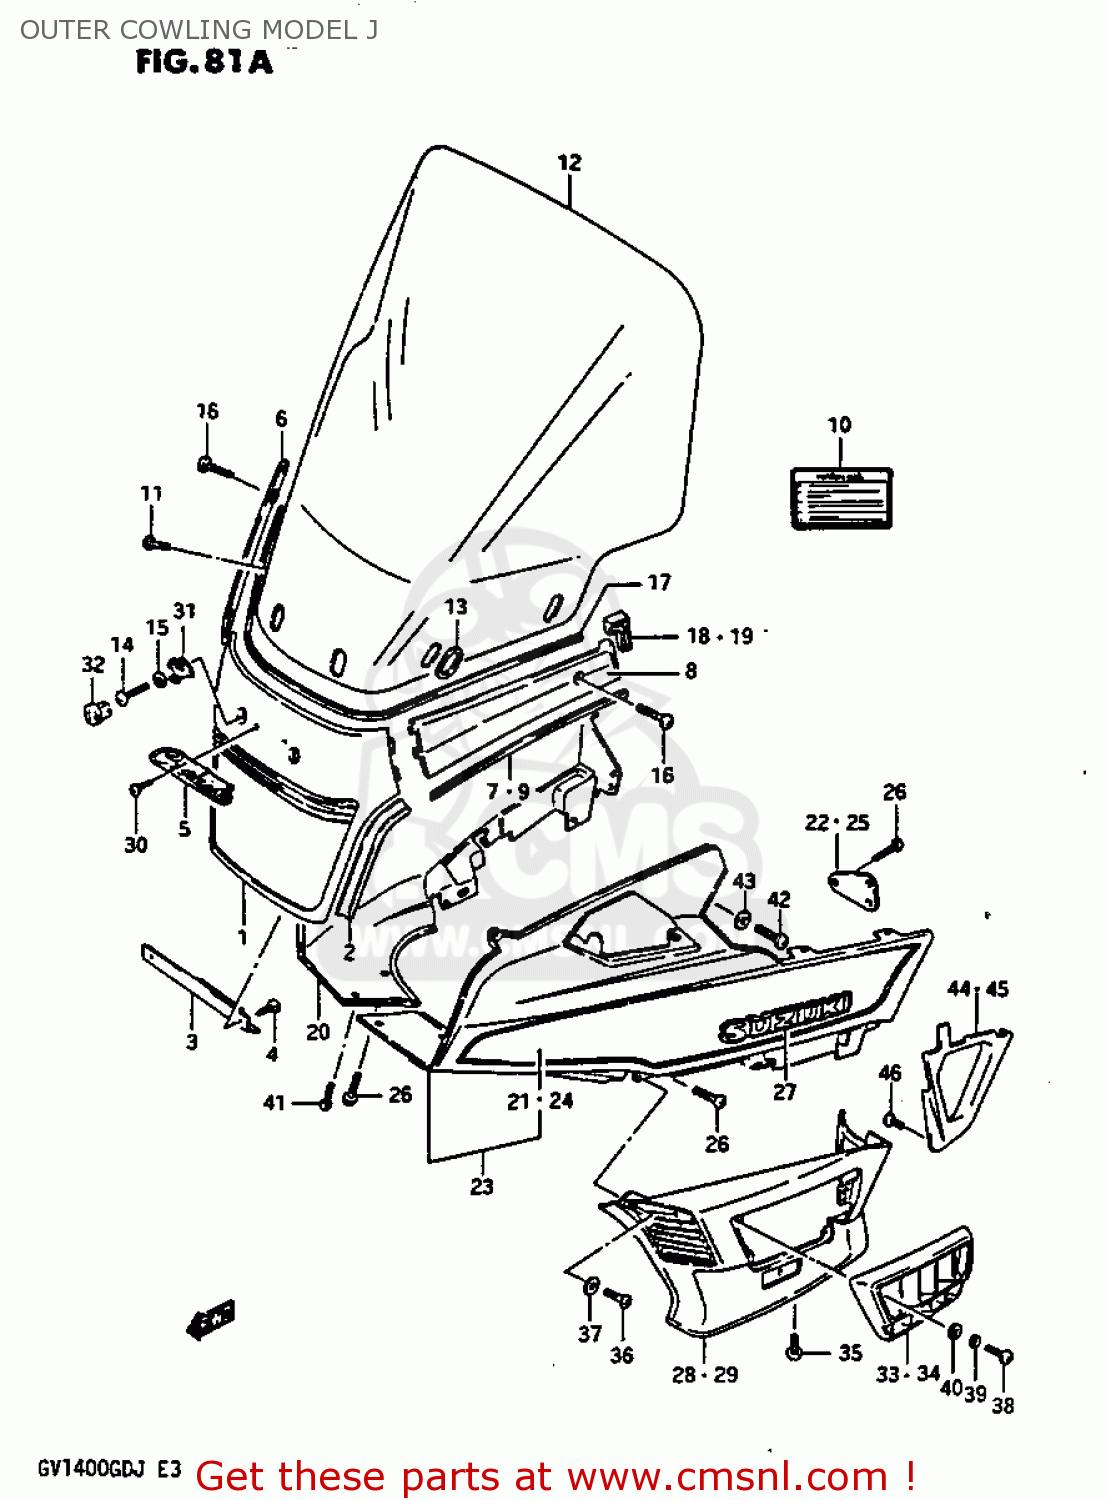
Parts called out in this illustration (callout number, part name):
1	COVER,COWLING,FRONT,CENTER
2	MOLDING,FRONT COVER,LOWER
3	BRACKET,FRONT,CENTER,UNDER
4	SCREW
5	EMBLEM,COWLING,FRONT
6	COVER,COWLING,FRONT,RIGHT
7	MOLDING,FRONT COVER SIDE
8	COVER,COWLING,FRONT,LEFT
9	MOLDING,FRONT COVER SIDE
10	LABEL (WARNING SCREEN)
11	SCREW
12	SCREEN ASSY,COWLING
13	WASHER,SCREEN
14	SCREW
15	WASHER
16	SCREW
17	SEAL,FRONT COVER,CENTER
18	CAP,COWLING FRONT COVER END
19	CAP,COWL FR COVER END,L
20	BODY COMP,COWLING,RIGHT
21	TAPE SET,COWLING
22	BRACKET,COWLING BODY,RIGHT
23	BODY,COWLING,LEFT
24	TAPE SET,COWLING
25	BRACKET,COWLING BODY,RIGHT
26	SCREW
27	EMBLEM,COWLING SIDE,LEFT
28	COVER ASSEMBLY,COWLING
29	COVER ASSEMBLY,COWLING SIDE,LEFT
30	SCREW
31	PLATE,FRONT COVER LOCK
32	CAP,FR COVER
33	LOUVER,SIDE COVER,RIGHT
34	LOUVER,SIDE COVER,LEFT
35	SCREW (M6X1X16)
36	SCREW
37	WASHER (4.3X13X0.80)
38	SCREW
39	LOCK WASHER
40	WASHER
41	SCREW
42	SCREW
43	WASHER
44	UNDER COVER, FRAME
45	COVER,COVER FRAME,UPPER
46	SCREW
47	COVER,COWLING SIDE,LOWER
48	COVER,COWLING SIDE,LOWER
49	BRACKET,COWLING SIDE,LOWER
50	BRACKET,COWLING SIDE,LOWER
51	WASHER
52	SCREW 5X10
